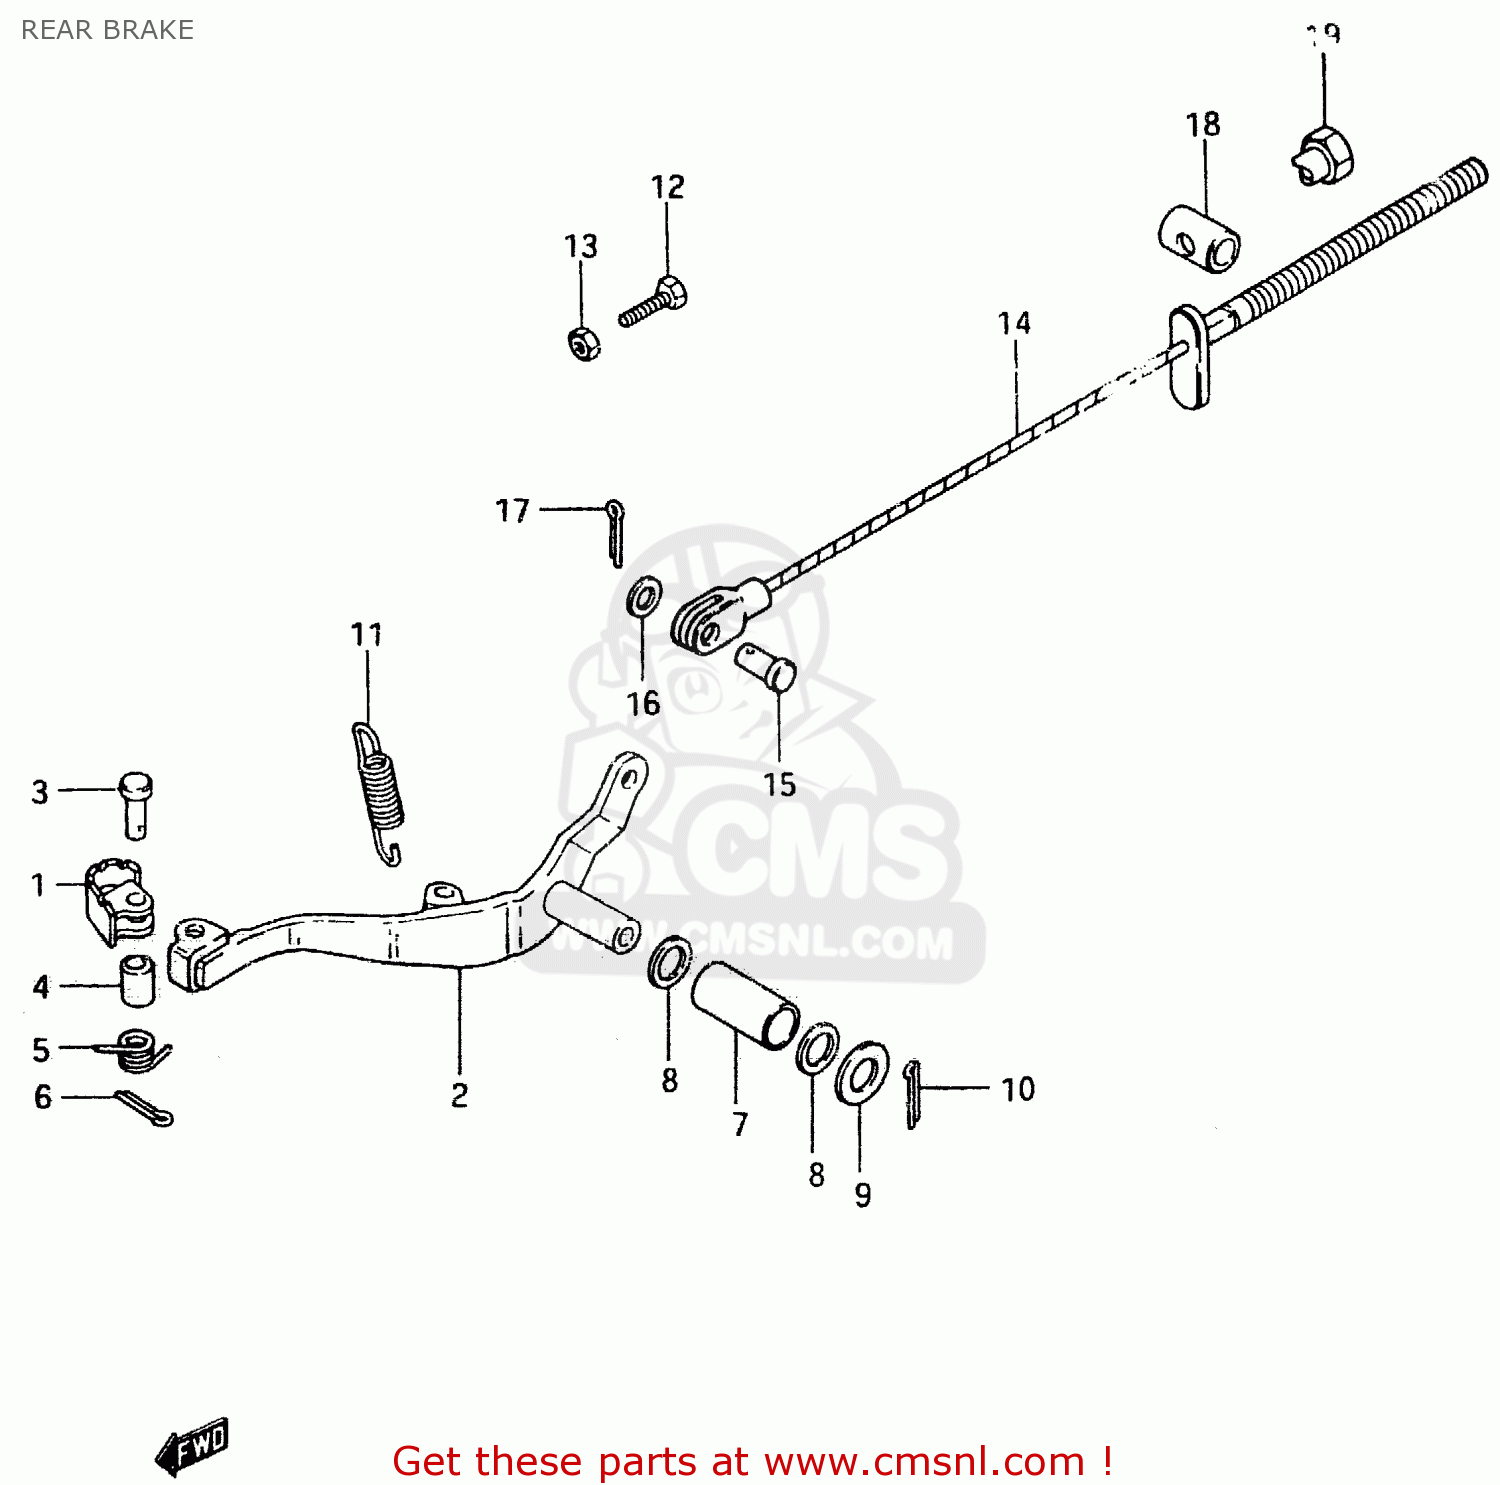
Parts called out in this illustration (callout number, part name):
1	PEDAL,BRAKE
2	ARM,BRAKE PEDAL
3	PIN
4	SPACER(6.5X10.5X6.5)
5	SPRING
6	PIN
7	BUSHING
8	O RING(D:2.2,ID:11.8)
9	WASHER
10	PIN 30X20
11	SPRING
12	SCREW(6X23)
13	NUT
14	CABLE,RR BRAKE
15	PIN(L:17.5)
16	WASHER
17	PIN 20X20
18	PIN
19	NUT (6MM)
